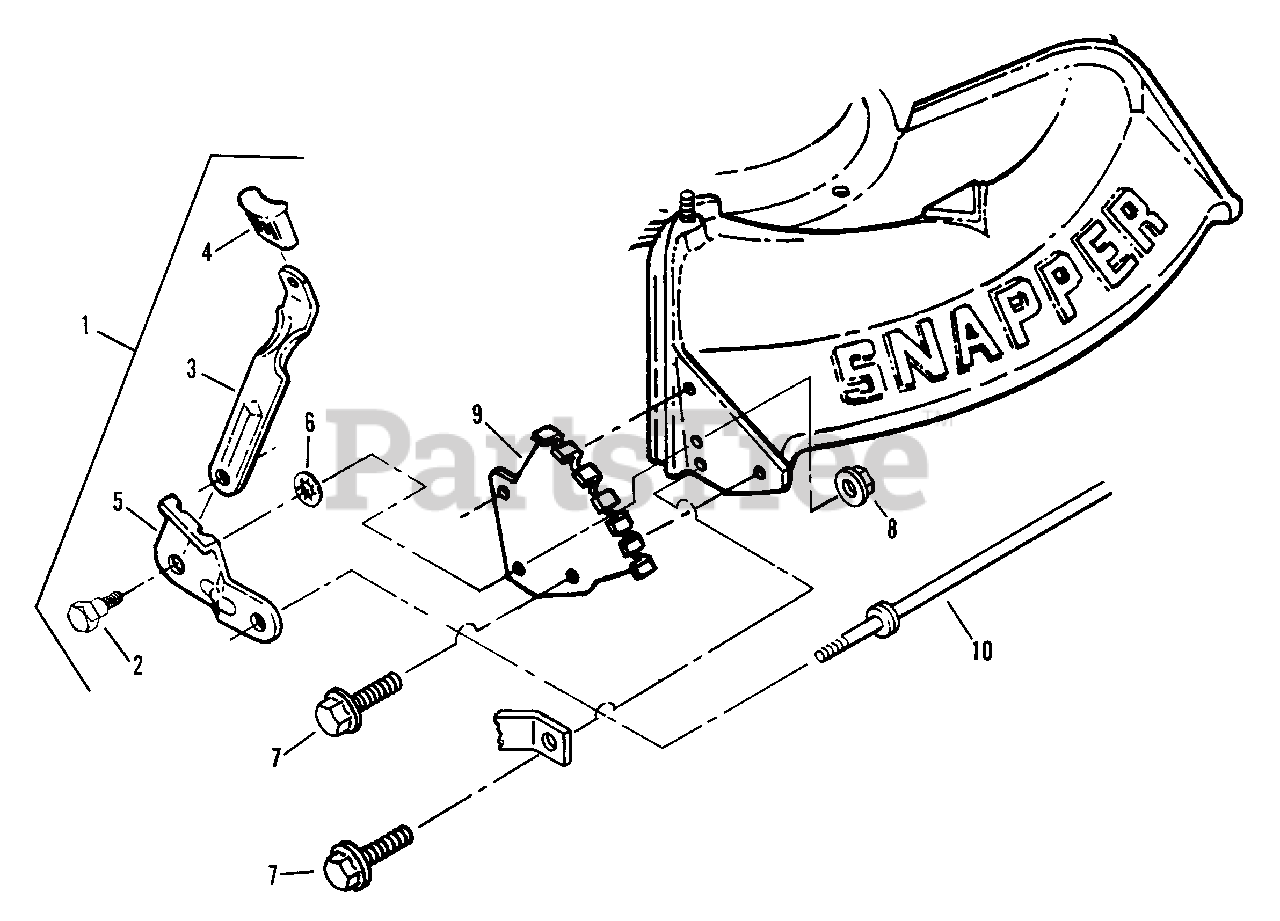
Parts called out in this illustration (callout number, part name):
1	ASSEMBLY, Arm Left Wheel
2	BOLT, 5/16-18 x 1" Shoulder
3	LATCH, Height
4	GRIP, Latch
5A	ARM, Left Wheel
5B	ARM, Right Wheel
6	RETAINER, 5/16 Bolt
7	SCREW, 5/16-18 x 5/8" Self-Tapping
8	NUT, 5/16-18 Hex Flange
9	BRACKET, Front Wheel
10	AXLE
